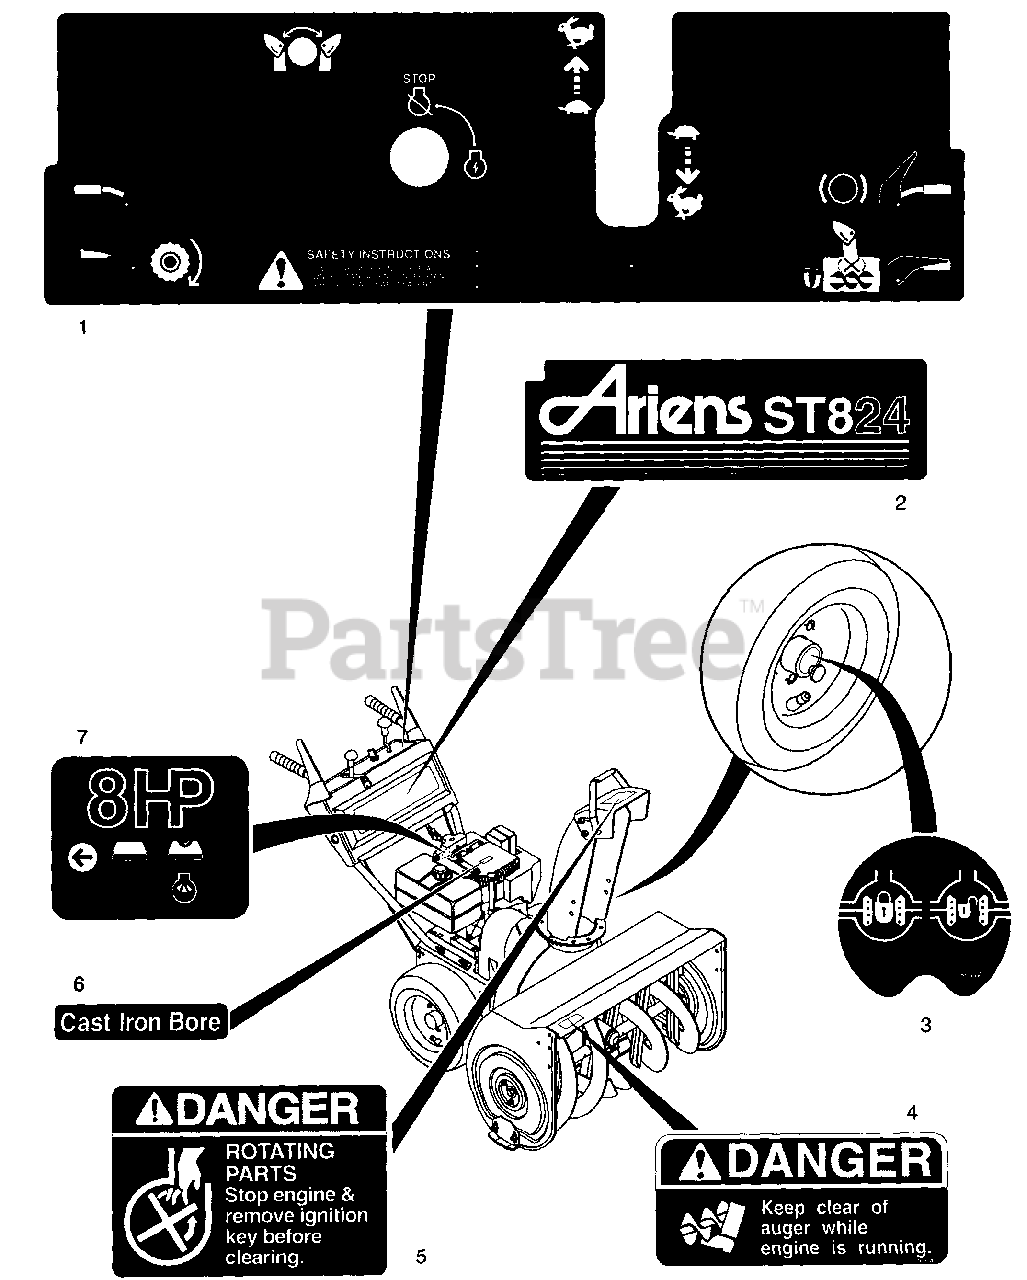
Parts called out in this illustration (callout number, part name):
1	DECAL-DASH
2	DECAL 824
3	DIFFERENTIAL LOCK DECAL
4	DECAL - DANGER
5	DECAL-DANGER ROTATING PARTS
6	DECAL - CAST IRON BORE
7	DECAL 8 HP & PRIMER
